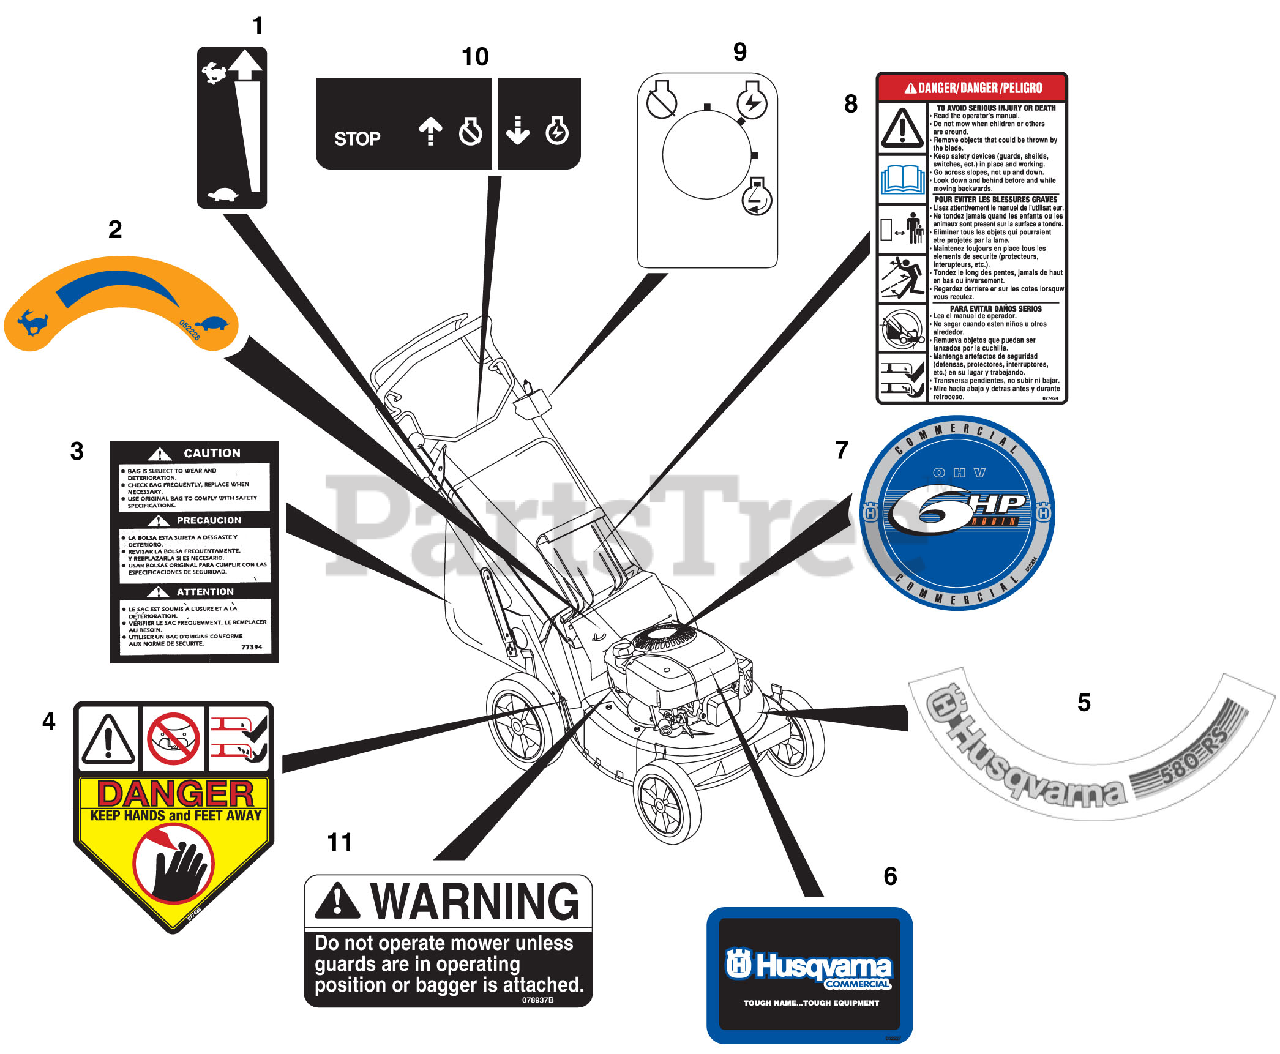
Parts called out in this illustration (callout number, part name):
1	Decal-Speed Control
2	Decal-Swoosh Husqvarna
3	Label-Bagger 21"
4	Decal-Danger
5	Decal-580 RS
6	Decal-Husqvarna & Robins (600 C)
7	Decal-Robin 6HP OHV-Commercial (600 C)
8	Decal-Bilingual Danger
9	DECAL-KEY SWITCH
10	Decal-Engine Control
11	DECAL-WARNING
